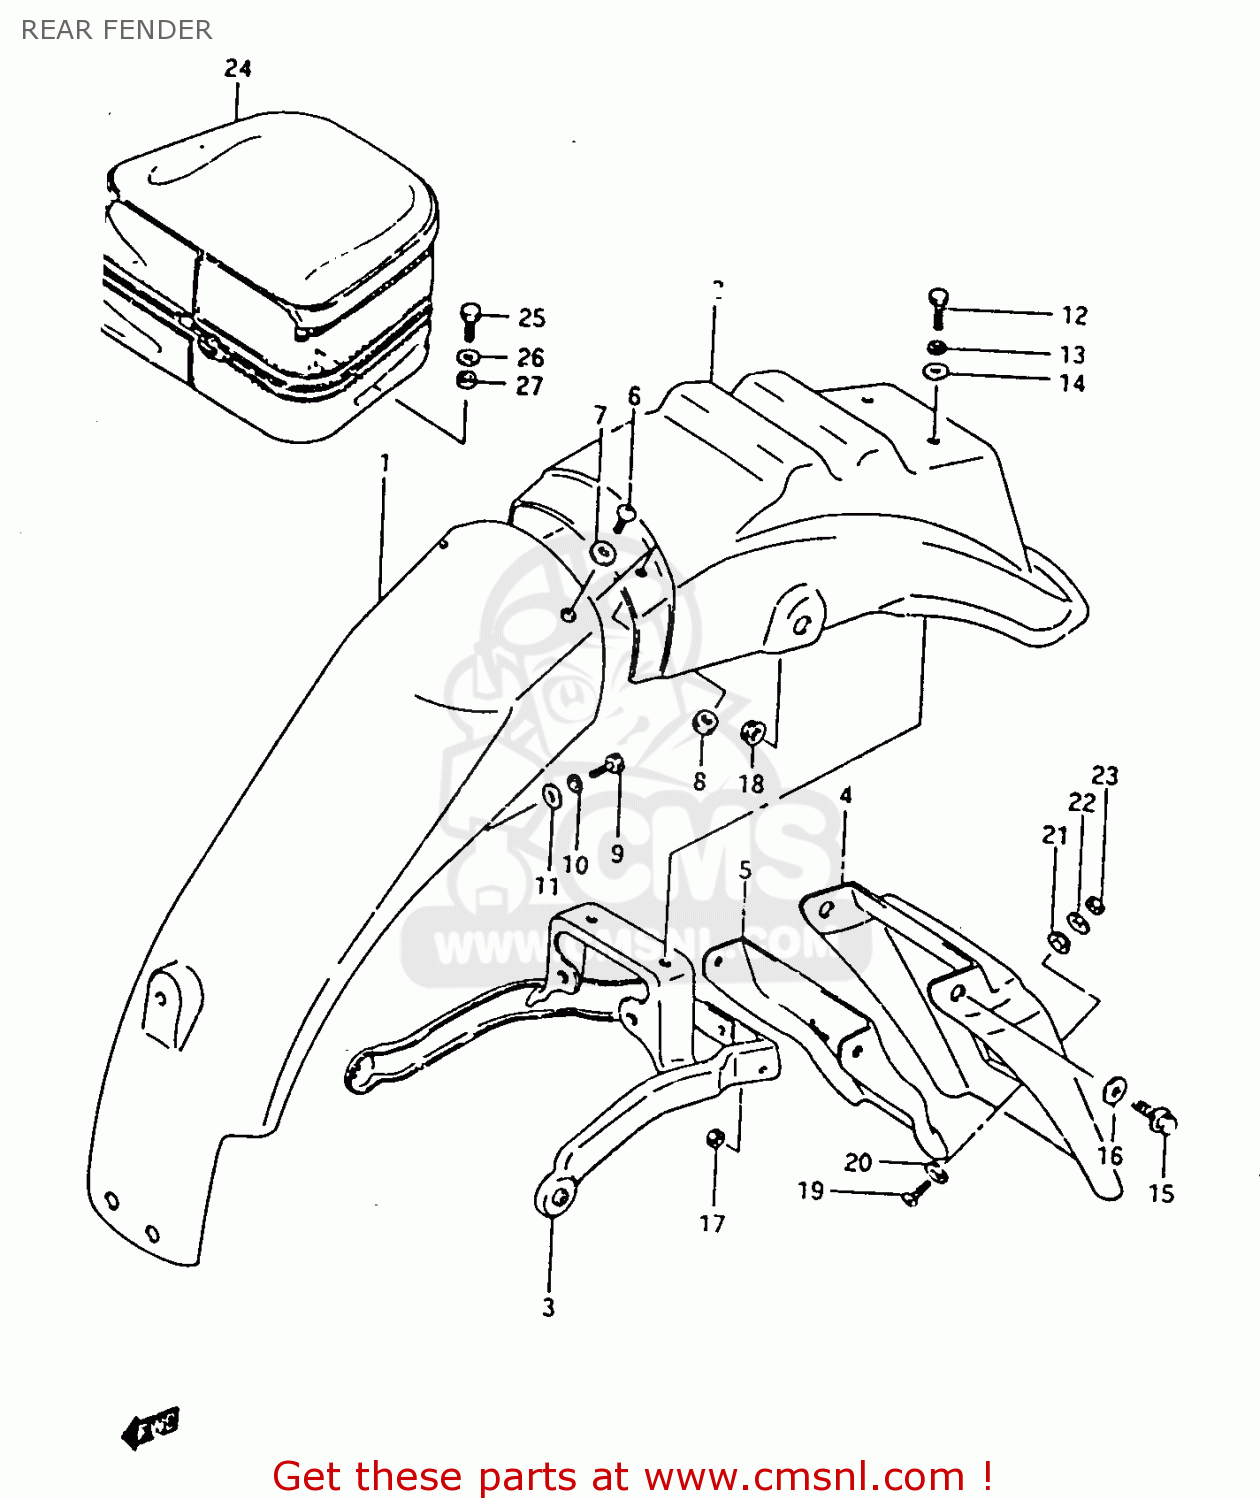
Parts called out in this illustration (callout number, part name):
1	BODY,REAR FENDER,FRONT
2	BODY, REAR (BLUE)
3	REINFORCEMENT,REAR FENDER
4	EXTENSION,REAR FENDER
5	REINFORCEMENT,REAR FENDER EXTENSION
6	SCREW, FRONT & REAR
7	WASHER
8	NUT 8MM
9	BOLT 6X16
10	WASHER,LOCK
11	WASHER
12	BOLT
13	WASHER,LOCK
14	WASHER
15	BOLT
16	WASHER
17	NUT
18	NUT
19	SCREW 6X12
20	WASHER
21	WASHER
22	WASHER
23	NUT
24	BAG ASSY, SEAT TAIL (BLUE/WHITE)
25	BOLT
26	WASHER
27	SPACER
